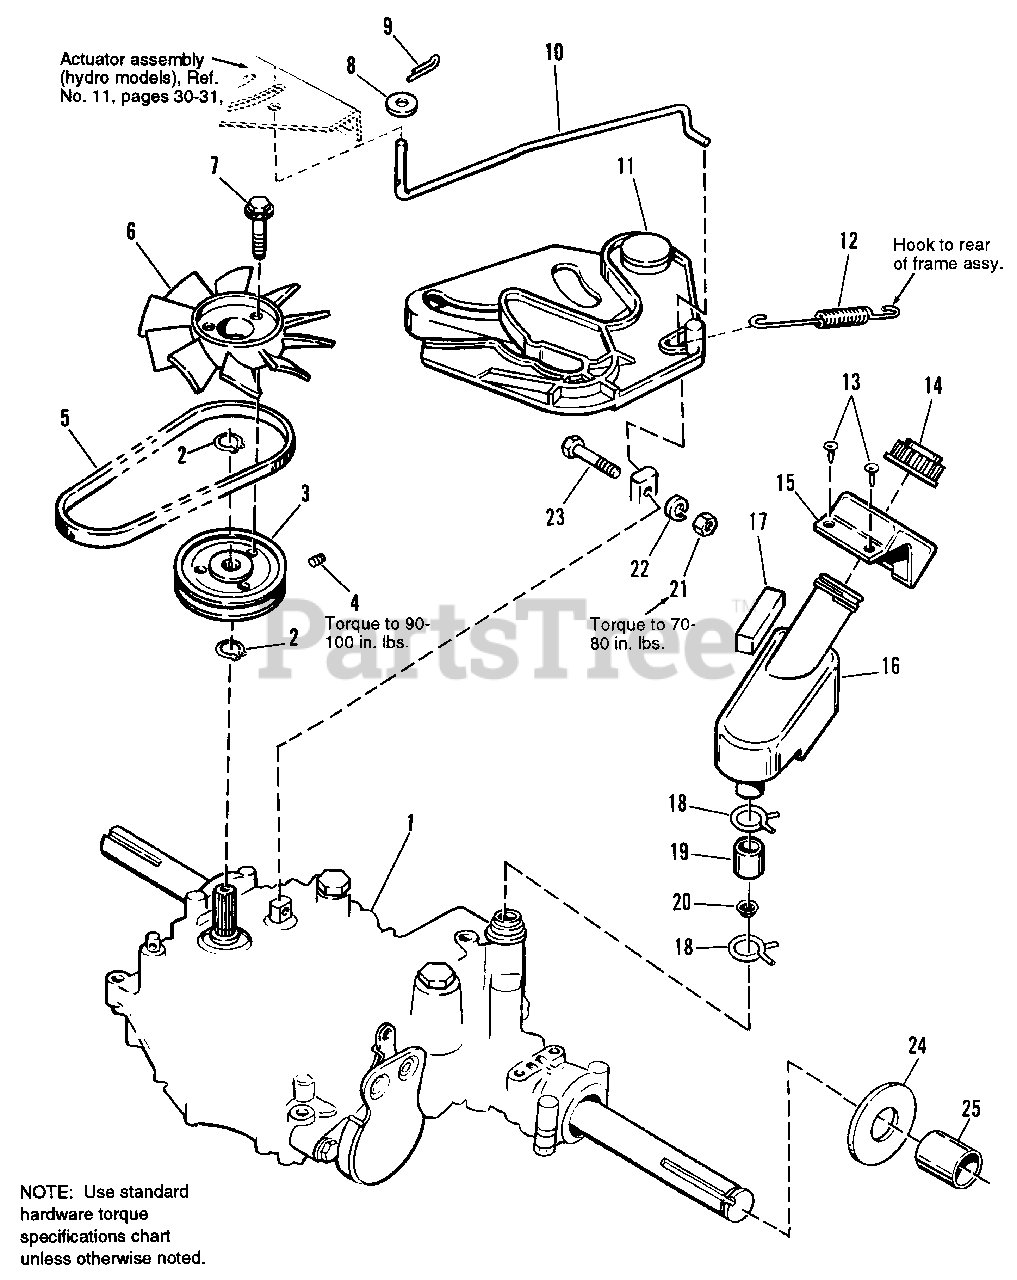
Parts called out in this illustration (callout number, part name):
1	TRANSAXLE, Tuff Torque
3	PULLEY, Driven
4	SETSCREW, 5/16-18 x 5/16
5	BELT, Drive
7	SCREW, Taptite, 1/4-20 x 1-1/8
8	WASHER, 11/32 x 3/4 x 1/16
9	COTTER PIN, 15/16 x 1
10	ROD, Return-to-Neutral
13	FASTENER, Panel
14	CAP, Filler
16	TANK, Expansion Chamber
18	CLAMP, Hose
20	SCREEN, Filter
21	NUT, Hex, 6 mm
22	LOCKWASHER, 1/4
23	SCREW, Hex, 6 mm-1 x 55 mm
24	WASHER, 1" I.D., 2-1/4" O.D.
25	SPACER, 1-1/2" Long
